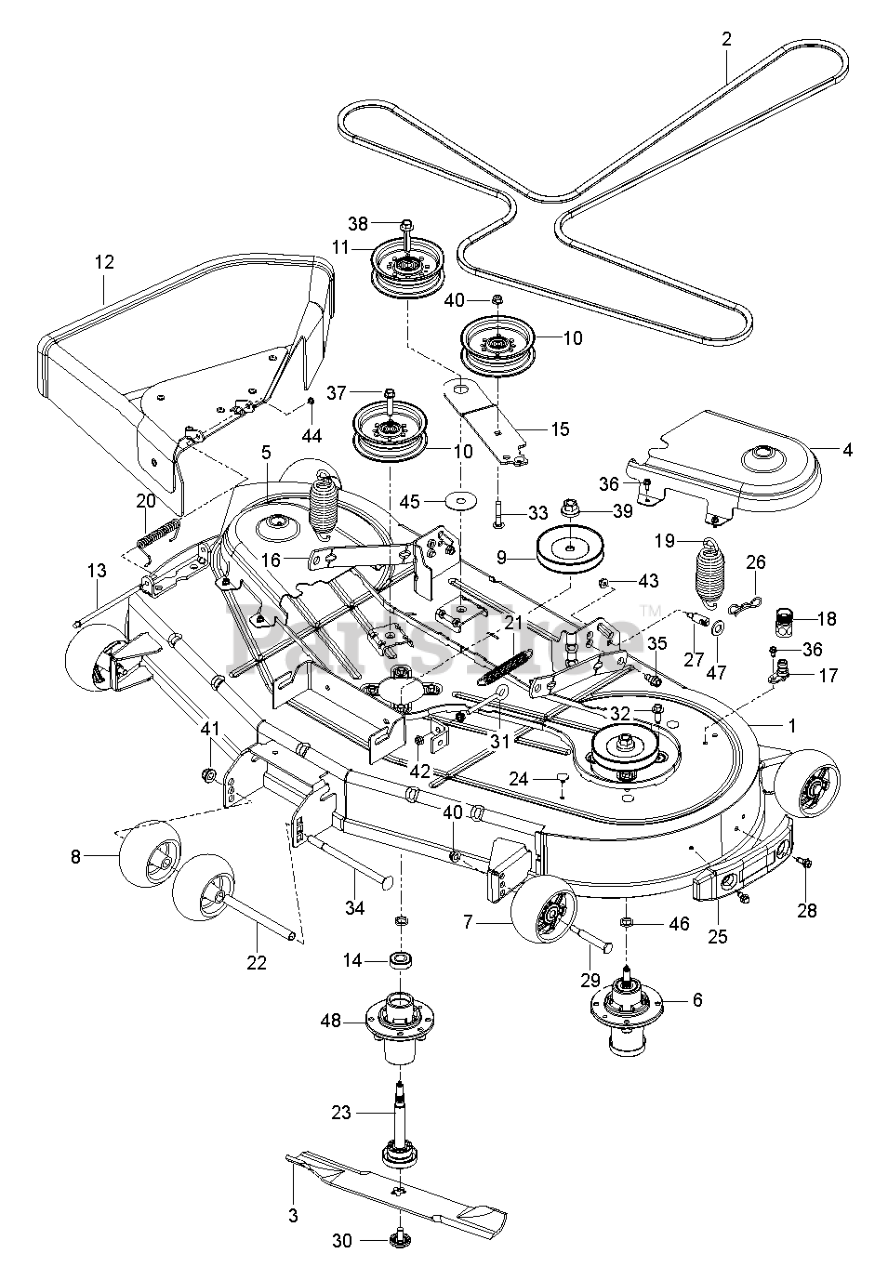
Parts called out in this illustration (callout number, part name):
1	DECK SVC.54.CLRCT.RZ.MS668
2	BELT.54CC.DRIVE.DECK.RZ.LONG
3	BLADE CC54 PZ STYLE HI LIFT BL
4	COVER.PNT.54CC.MNDRL.LH.ZTR.GY
5	COVER 54 CLEARCUT RH MANDREL G
6	MANDREL ASM, CAST IRON
7	WHEEL.GAUGE.RALLY
8	ROLLER, GAUGE .635 BORN
9	PULLEY.MANDREL.CRD 107CM.DOM.
10	PULLEY.IDLER.2006
11	RB PULLEY.IDLER.4.50/HUB SPEC
12	DEFLECTOR ASSY 54 CLEARCUT RES
13	ROD.HINGE
15	ARM IDLER ARM, CLEARCUT 54 BLA
16	ARM.RFIXED.MOWER.SUSPNSIONX431
17	PORT.WASHOUT
18	COUPLING.QUICK CONNECT
19	SPRING
20	SPRING.42.FCS.DEFLECTOR
21	SPRING.EXTN.42.FCS.TR.DECK.DRV
22	TUBE, ROLLER AXLE LONG
23	SHAFT ASM MANDREL
24	PLUG CHRISTMAS TREE
25	BUMPER ASSY 54 CLEARCUT TRIM S
26	PIN.COTTER.7/16.BOW TI.
27	STUD.FASTNER.W/ANTI-ROTATE
28	SHOULDER BOLT 5/16-18TT
29	BOLT.SHOULDER.3/8-16X3-5/8.
30	BOLT.WASHER.ASM.7/16-2
31	EYE BOLT 5/16 X 3.50
32	BOLT.HEX.WASHR.HED.313-18X1.19
33	BOLT
34	RHSNB 1/2-13 X 8 GR5 ZD
35	BOLT.SHOULDER
36	SCREW.1/4-20X5/8
37	SCREW LT
38	SCREW.7/16-14 X 2.125.WASHER
39	NUT.FLANGE.LOCK.TOP
40	NUT LOCK FLG 3/8-16 UNC
41	NUT, 1/2-13 HEX FLG NYLOC ZD
42	NUT 5/16C WHIZ
43	NUT LOCK HEX FLANGE 5/16-18
44	NUT PUSH M
46	WASHER.SPACER.MANDREL
47	WASHER.CLEAR.ZINC
48	MANDREL, HOUSING - CAST IRON
